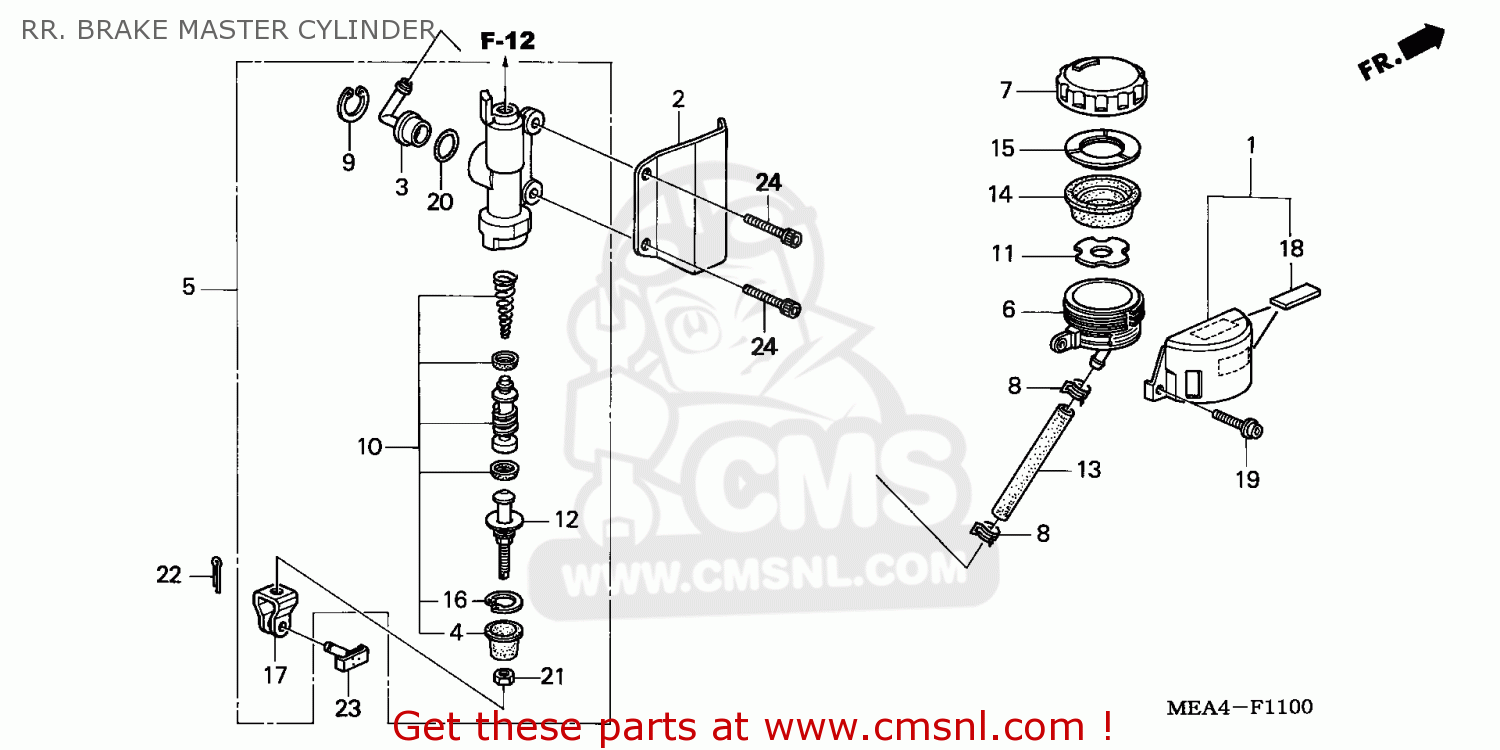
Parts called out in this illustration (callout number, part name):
1	COVER,RR BRAKE FL
2	COVER,RR M/C
3	CONNECTOR,MASTER
4	BOTTOM COMP.
5	SUB ASSY,RR M/C
6	CUP COMP.,OIL (NI
7	CAP,OILCUP
8	CLAMPER,MASTER CY
9	CIRCLIP
10	PISTON SET,M/C.
11	FLOAT,RR M/C
12	ROD COMP.,PUSH
13	HOSE,M/C OIL
14	DIAPHRAGH
15	PLATE,DIAPHRAGM
16	CIRCLIP, M/C.
17	JOINT,BRK ROD
18	CUSHION,NUMBER PL
19	BOLT,FLANGE SOCKE
20	O-RING,14.8X2.4
21	NUT,HEX.,8MM
22	PIN,COTTER 2.0X15
23	PIN D,JOINT
24	BOLT,SOCKET 6X25
